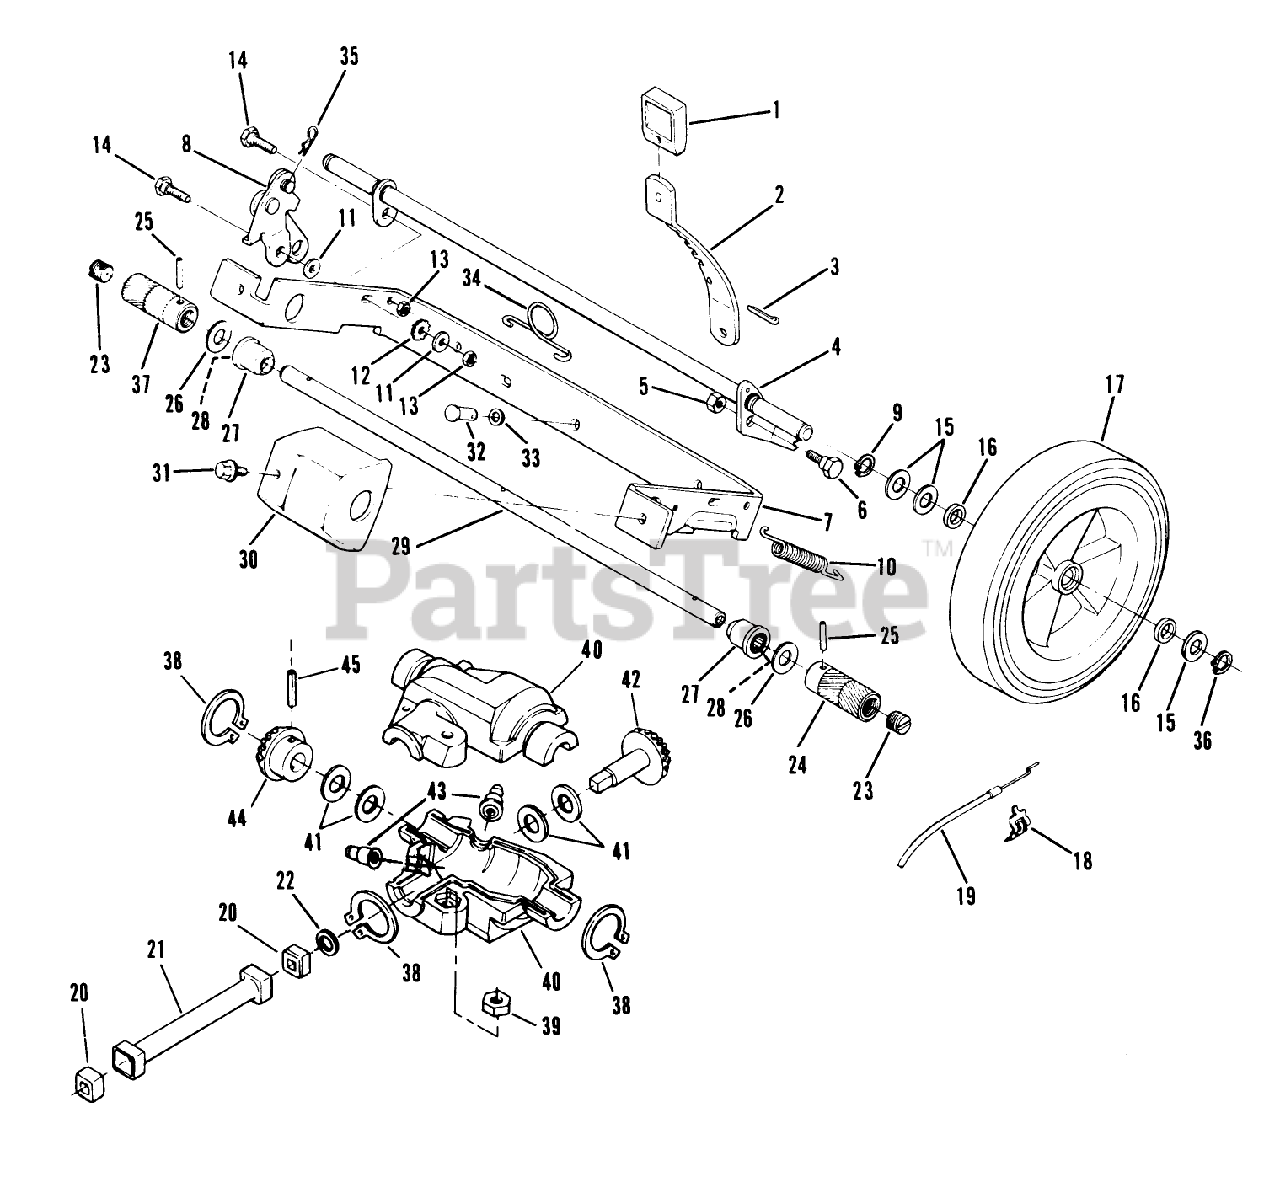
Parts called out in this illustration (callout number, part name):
1	KNOB
2	LEVER
5	LOCKNUT E
6	BOLT RB&W
7	BRK-21" AXLE
9	RET RING
10	SPRING
11	WASHER S
13	STOP NUT
14	BOLT RB&W
15	SPACER
16	WASHER
19	Cable-Starter Interlock
20	BUSHING
22	O-RING
23	GREASE PLUG
24	ROLLER-LH
25	PIN
28	BEARING AY F
29	DRIVE SHFT TAG AY
30	GUARD
32	PIN
33	WASHER SPRING LAR
34	SPRING N.A.S
36	RET RING
37	ROLLER-RH
39	LOCKNUT E
41	THRUST WASHER
43	ZERK FITTING
45	ROLL PIN
